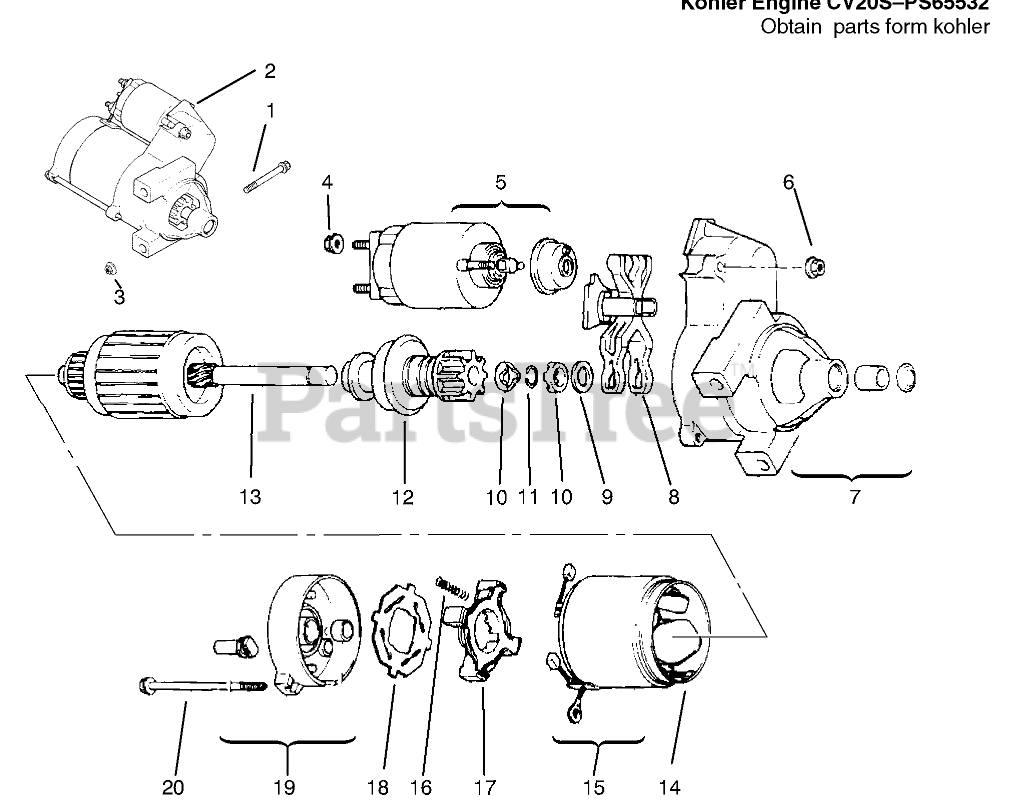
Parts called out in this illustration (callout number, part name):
2	Starter INC 4-20
3	Nut
4	Nut
5	Solenoid
6	Nut
7	Cap Drive End
8	Lever Starter Drive
9	Washer-Thrust
10	Nut
11	Ring-Retainer
12	Drive Pinion
13	Armature
14	Frame
15	Brush Kit
16	Spring Brush
17	Holder-Brush
18	Insulator
19	Cap-Commutator End
20	Bolt
